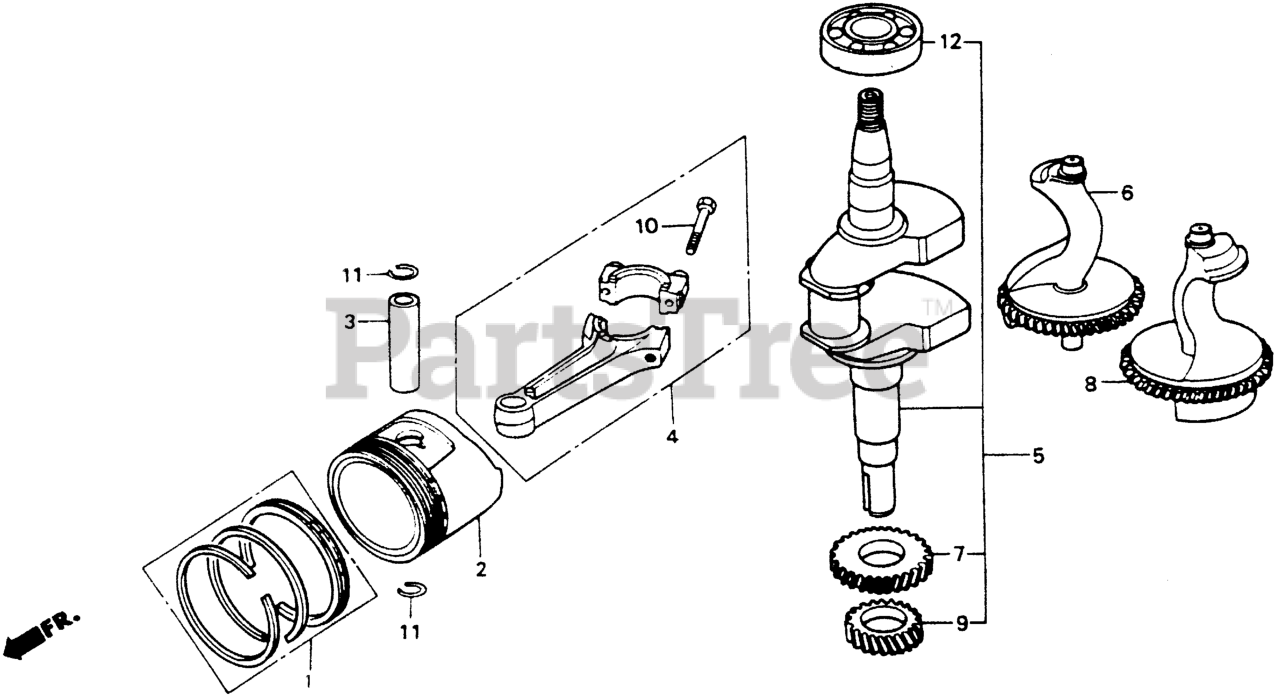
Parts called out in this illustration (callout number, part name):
1	RING SET, PISTON (STD)
1	RING SET, PISTON (STD) (NIPPON) (NOT AVAILABLE)
1	RING SET, PISTON (OS 0.25) Use up to Engine SN 1065100.
1	RING SET, PISTON (OS 0.25)
1	RING SET, PISTON (0.25)
1	RING SET, PISTON (OS 0.50) Use up to Engine SN 1065100.
1	RING SET, PISTON (OS 0.50)
1	RING SET, PISTON (0.50)
1	RING SET, PISTON (OS 0.75) Use up to Engine SN 1065100.
1	RING SET, PISTON (0.75)
2	PISTON (STD)
2	PISTON (OS 0.25)
2	PISTON (OS 0.50)
2	PISTON (OS 0.75)
3	PIN, PISTON
4	ROD ASSY., CONNECTING
4	ROD ASSY., CONNECTING (US)
5	CRANKSHAFT (NOT AVAILABLE)
6	WEIGHT A, BALANCER (NOT AVAILABLE)
7	GEAR, BALANCER DRIVE
8	WEIGHT B, BALANCER
9	GEAR, TIMING
10	BOLT, CONNECTING ROD
11	CLIP, PISTON PIN (18MM)
12	BEARING, RADIAL BALL (6206)
